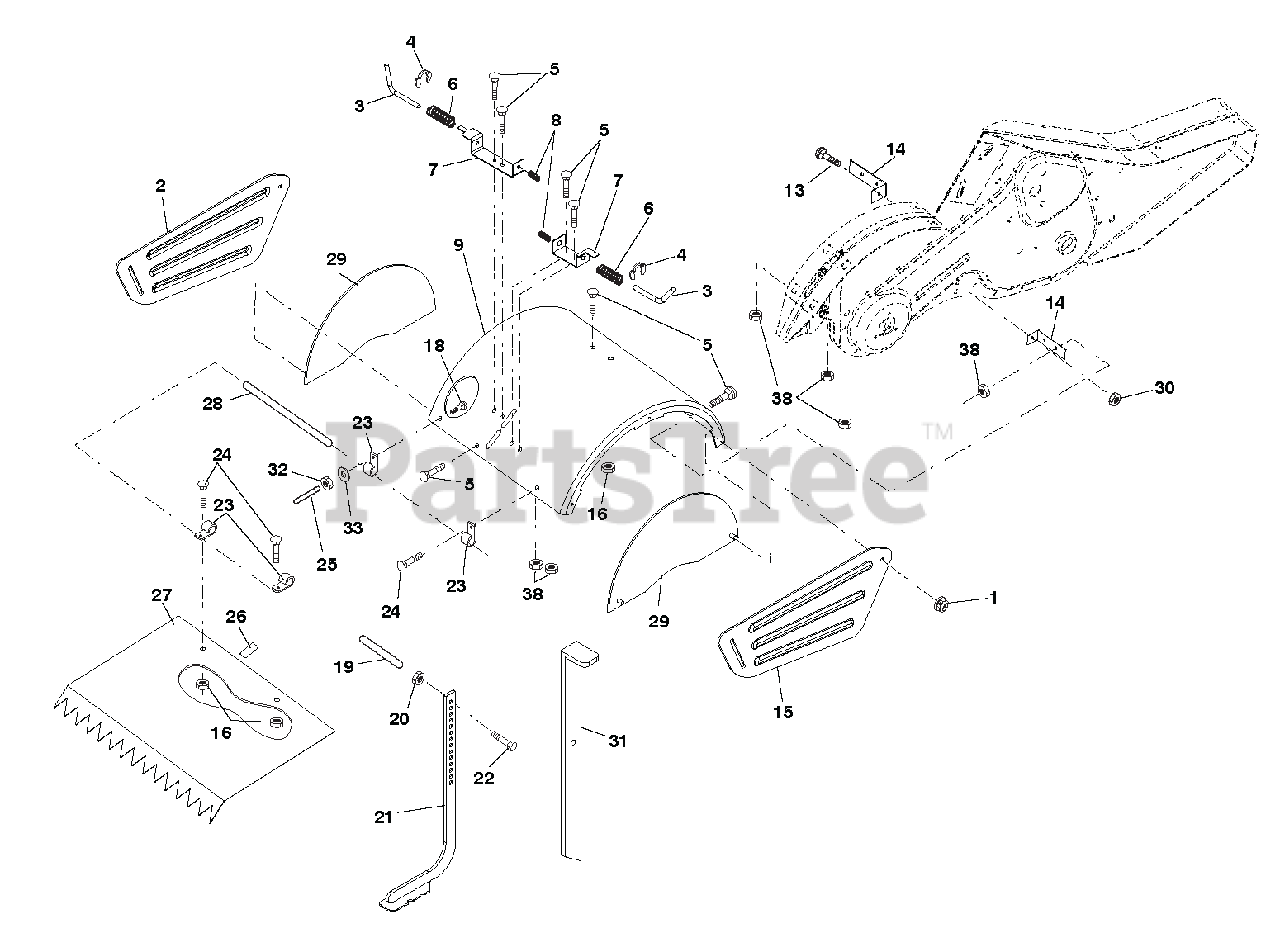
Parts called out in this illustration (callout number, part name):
1	Nut, Lock Hex Flange 5/16-18 u
2	SHIELD, SIDE, OUTER RH
3	Pin, Stake, Depth
4	Ring, Klip
5	Bolt, Carriage, Gr. 5 5/16-18
7	Bracket, Latch
8	Spring, Depth Stake
9	SHIELD, TINE
13	Bolt, Carriage 5/16-18 x 1-1/4
14	Bracket, Shield Tine
15	SHIELD, SIDE, OUTER RH
16	Nut, Hex Flange 1/4-20 unc
18	Bolt, Carriage 1/4-20 x 1-1/4
20	Nut, Hex 3/8-16
21	Stake, Depth
22	Bolt, Hex 3/8-16 x 2
24	Bolt, Carriage 1/4-20 x 1/2
25	Cap, Vinyl
26	Pad, Idler
27	SHIELD, LEVELING
28	Pin, Hinge
29	SHIELD, SIDE
30	Nut, Hex, Flangelock
31	STAKE, DRAG
32	Nut, Fin, Hex 1/4-20 unc
33	Washer, Lock 1/4
38	Nut, Keps 5/16-18 unc
